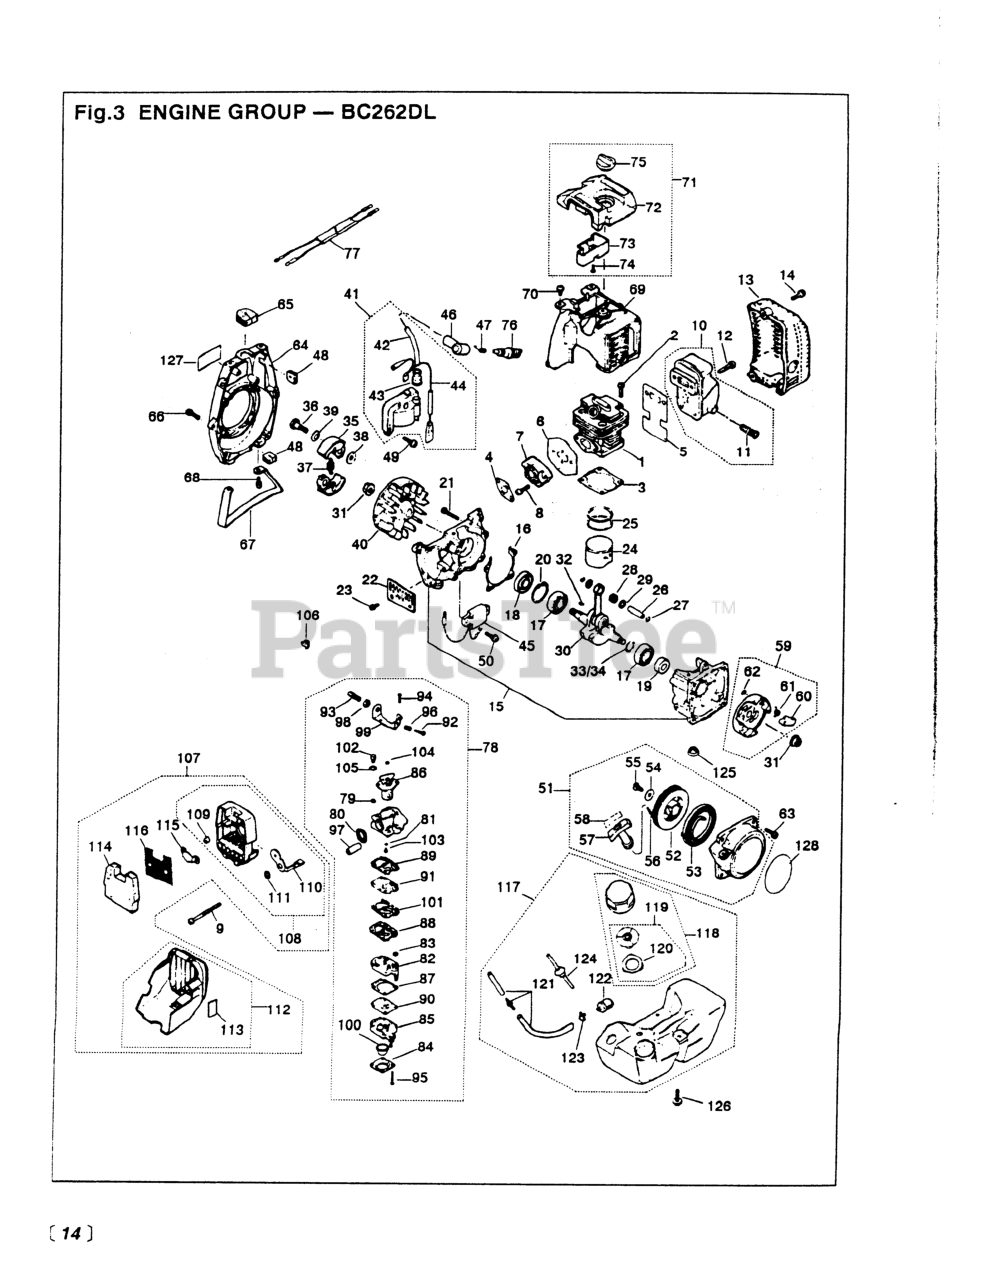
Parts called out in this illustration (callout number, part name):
1	CYLINDER (NLA)
7	INSULATOR (RPLS -13161)
8	SCREW, M5X20 (RPLS.1400-75510)
11	ARRESTER (RPLS 5850-15140)
12	SCREW
13	COVER, MUFFLER
15	CRANKCASE ASSEMBLY
19	SEAL, OIL (RPLS 1200-21220)
20	RING, SNAP, M32 x 1.2
21	BOLT, M5 X 30
23	SCREW, M5 X 12
24	PISTON
25	RING, PISTON
26	PIN, PISTON
27	RING, SNAP (RPLS 1101-41320)
28	BEARING
29	WASHER, THRUST (NLA)
30	CRANKSHAFT COMP
32	KEY
33	SHIM (NO LONGER AVAILABLE)
36	BOLT
38	WASHER, FLAT (USE 182303)
41	COIL ASSEMBLY
42	CORD HIGHTENS (NLA)
43	CAP
45	UNIT (RPLS -71310)
46	CAP, PLUG
47	SPRING PLUG (RPLS 3310-71320)
50	SCREW, M5 x 16
51	RECOIL ASSEMBLY
52	REEL
53	SPRING, SPIRAL
55	SCREW (RPLS -75150)
57	KNOB
59	PULLEY ASSEMBLY
60	RATCHET
61	SPRING, RETURN
62	E-RING
63	SCREW, M5X20 (RPLS.1400-75510)
64	COVER, FAN (RPLS -31111)
68	BOLT (REPLACES 01252-30514)
69	COVER (RPLS -32111)
70	SCREW, M5 X 12
71	COVER (NLA) (RPLS -33100)
72	COVER, HEAD (NLA)(RPLS -33110)
74	SCREW
75	KNOB (RPLS 1600-33140)
77	CORD
78	CARBURETOR
79	RING
80	RING, PACKING (NLA)
81	RING, O
84	COVER
85	BODY
86	VALVE ASSY (NO LONGER AVAIL)
87	KIT ONLY
88	GASKET, PLATE
89	GASKET, PUMP
90	DIAPHRAGM (USE 4810-81260)
91	DIAPHRAGM
92	SCREW, IDLE AD
93	SCREW, CABLE
94	SCREW
95	SCREW
96	SPRING, IDLE A
97	SLEEVE, MOUNT
98	NUT, CABLE ADJUSTER
99	BRACKET, IDLE
100	PUMP, PRIMING
101	PLATE, PUMP (NLA)
102	SWIVEL (USE -06040)
103	JET (RPLS -81250)
104	PLUG NEEDLE
105	WASHER
106	CAP, CABLE END
107	CLEANER ASSY (USE -82004)
109	SLEEVE
112	COVER, AIR FILTER (RPLS -82201
113	LABEL
115	PLATE
119	VALVE COMPLETE
120	PACKING (RPLS -85321)
122	FILTER ASSY
123	CLIP (REPLACES 2841-31280)
125	WASHER
126	SCREW, M5 X 22
128	LABEL (NLA)
